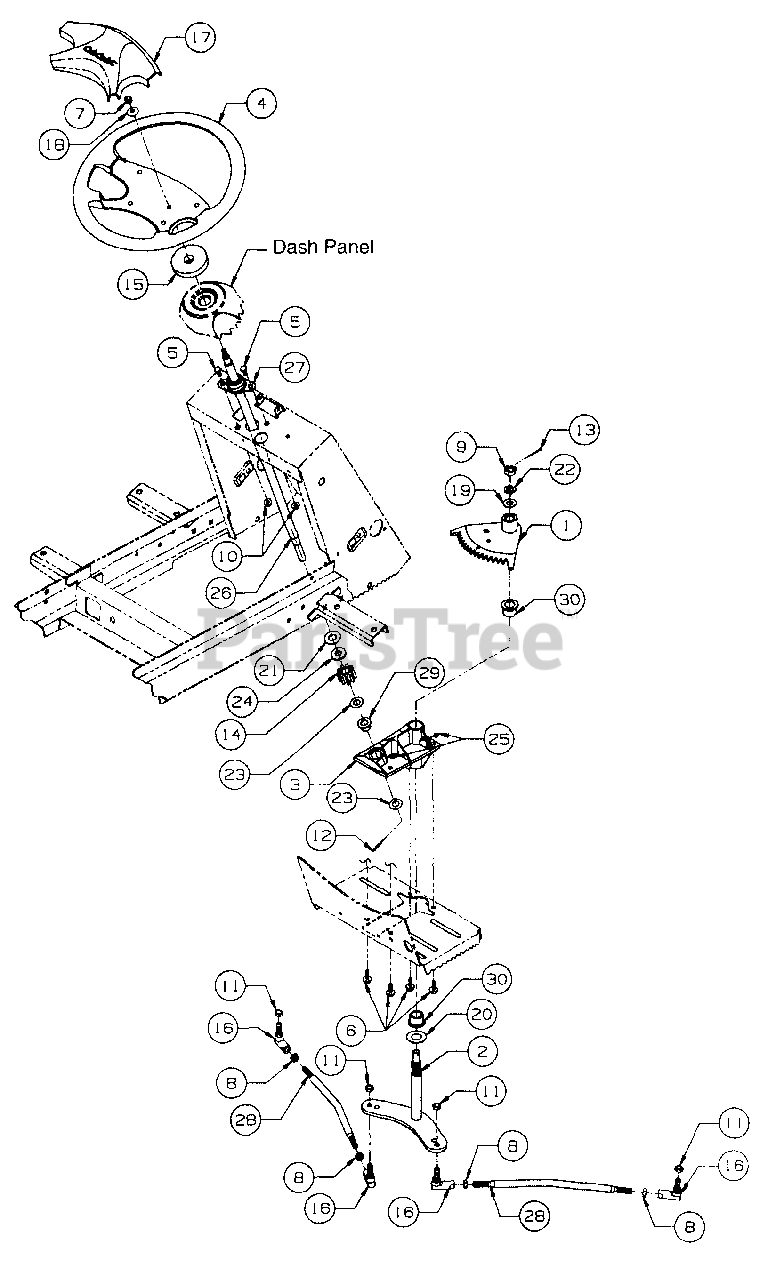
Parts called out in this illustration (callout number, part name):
1	Segment Assy, 18T Steering
2	Arm Assy, Lower Steering
3	Housing Assy,
4	Wheel, Steering
5	Screw, Hex Cap, 1/4 - 20 x .62, GR5
6	Screw, Hx Wsh Hd-TPTT, 5/16-18 x .75
7	Nut, Hex Center Lock, 5/16-24
8	Nut, Hex Jam, 3/8-24 GR5
9	Nut, Hex Slotted, 1/2-20 GR5
10	Nut, Hex Flange Lock, 1/4-20
11	Nut, Hex Lock, 3/8-24 GR5
12	Pin, Cotter, 1/8 Dia x 1
13	Pin, Cotter, 3/32 Dia x 1.25
14	Pinion, Steering
15	Gasket, Steering
16	Joint, Ball, 3/8-24
17	Insert, Steering Wheel
18	Washer, Bell, .340 x .88 x .06 Thk
19	Washer, Flat, .510 x 1 x .06 Thk
20	Washer, Flat, .760 x 1.5 x .03 Thk
21	Washer, Flat, .56 x 1 x .04 Thk
22	Washer, Lock, 1/2
23	Washer, Flat, .531 x 1 x .027 Thk
24	Wshr, Rubber Flat, .50 x 1.12 x .125 Thk
25	Fitting, Grease, 3/16 Drive Type
26	Shaft, Steering
27	Bearing, Flange
29	Bearing, Flange, .503 ID
30	Bearing, Bronze Flange, .75 ID
